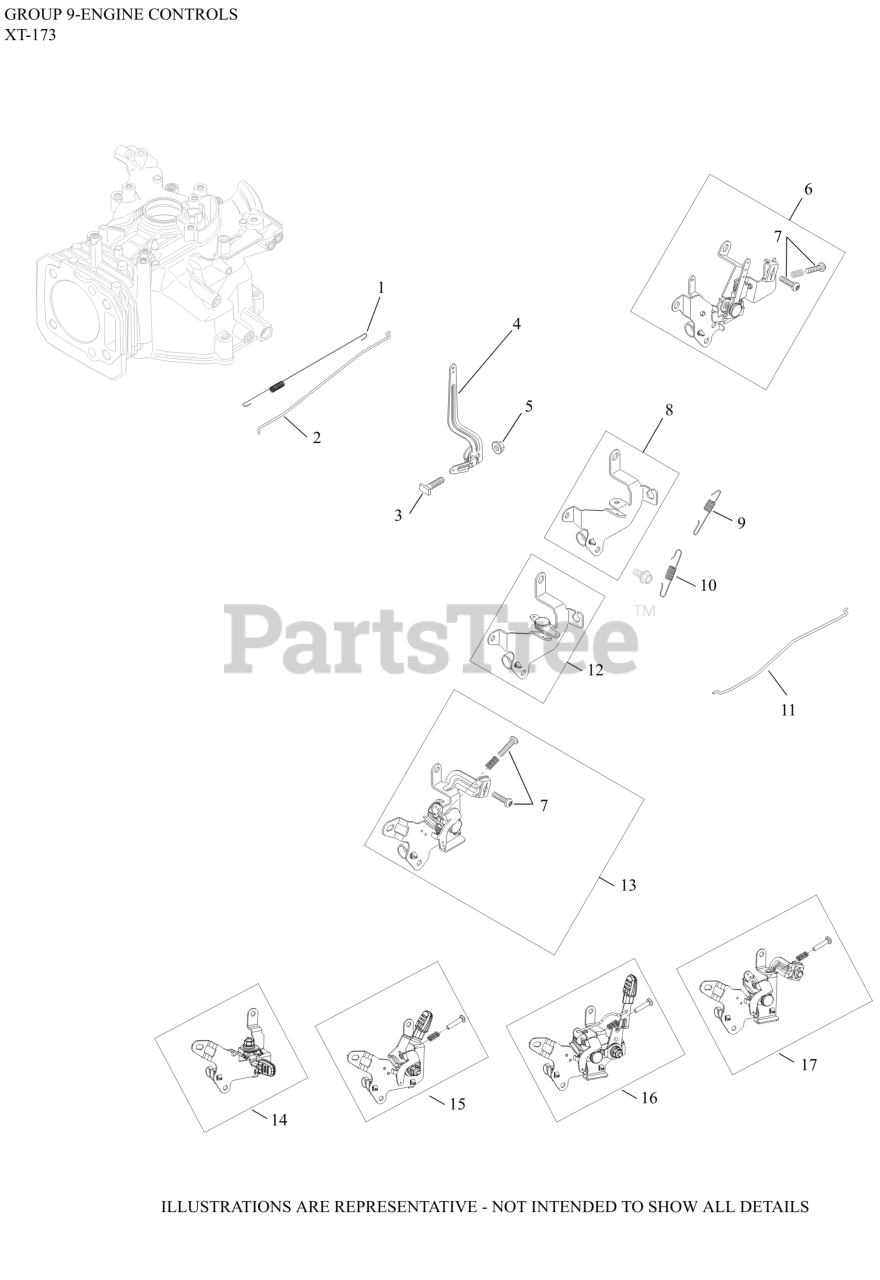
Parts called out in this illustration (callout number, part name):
1	SPRING, LINKAGE
2	LINKAGE, GOVERNOR
3	SCREW, RECTANGLE HEAD (M6)
4	LEVER, GOVERNOR-USE 14 090 37-S
7	SCREW, #25 6-LOBE PAN HD (M5)
10	SPRING, GOV (3301-3800 RPM)
11	LINKAGE, CHOKE
13	CONTROL ASSEMBLY (VAR. SPEED)
NI	SCREW, (M5) HEX FLANGE
NI	SCREW, HEX FLANGE (M6)
